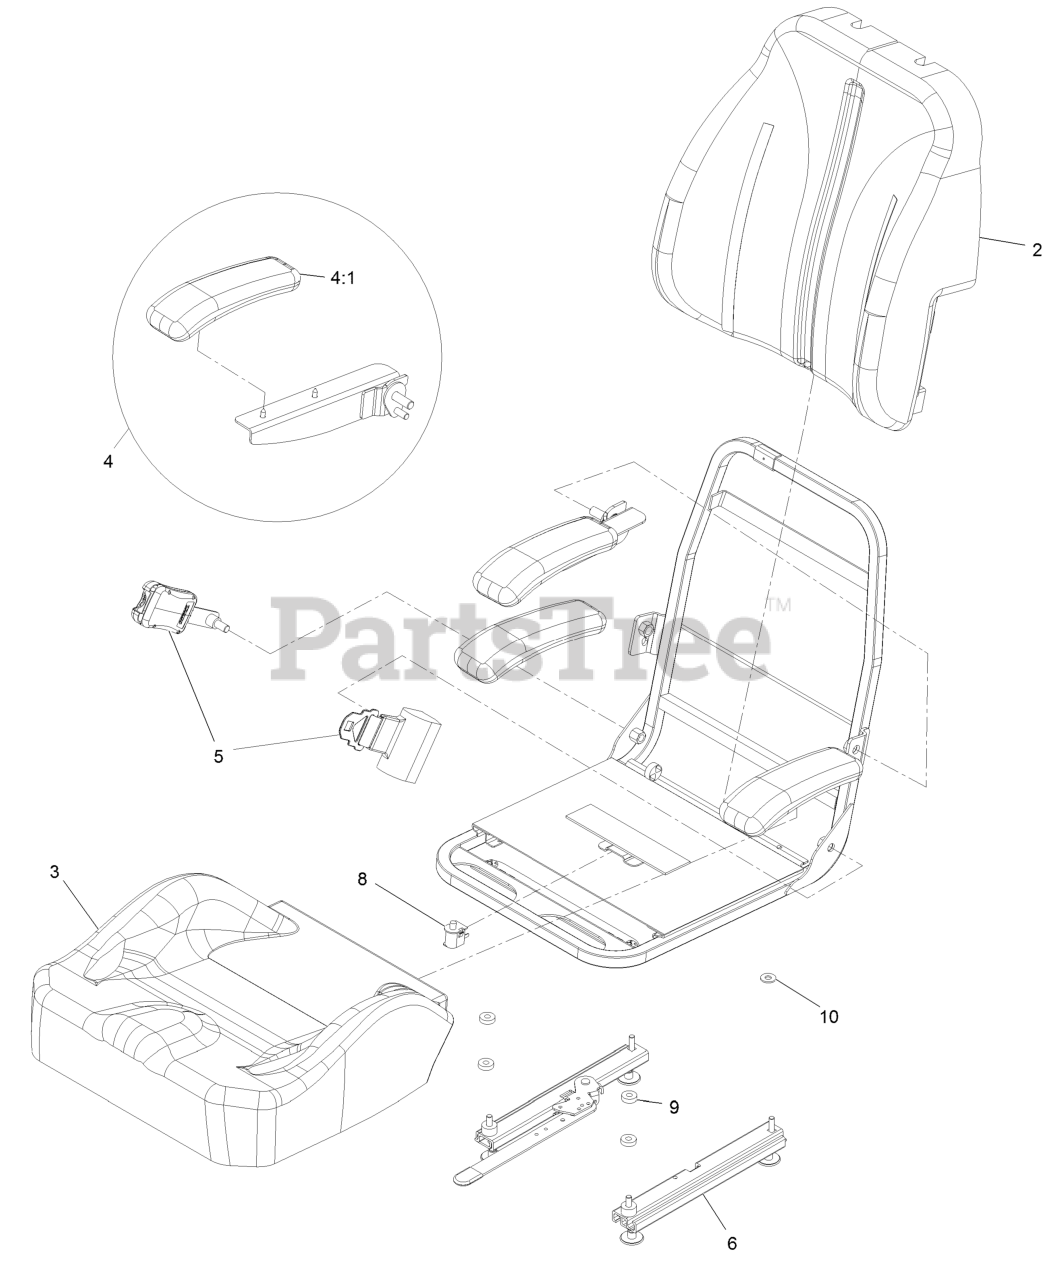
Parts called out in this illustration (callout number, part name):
2	COVER-SEAT BACK
3	COVER-SEAT CUSHION
4	ARMREST KIT
4:1	CUSHION-REST, ARM
5	KIT-SEAT BELT SERVICE
6	TRACK-SEAT
8	SWITCH-BAIL
10	WASHER-FLAT
